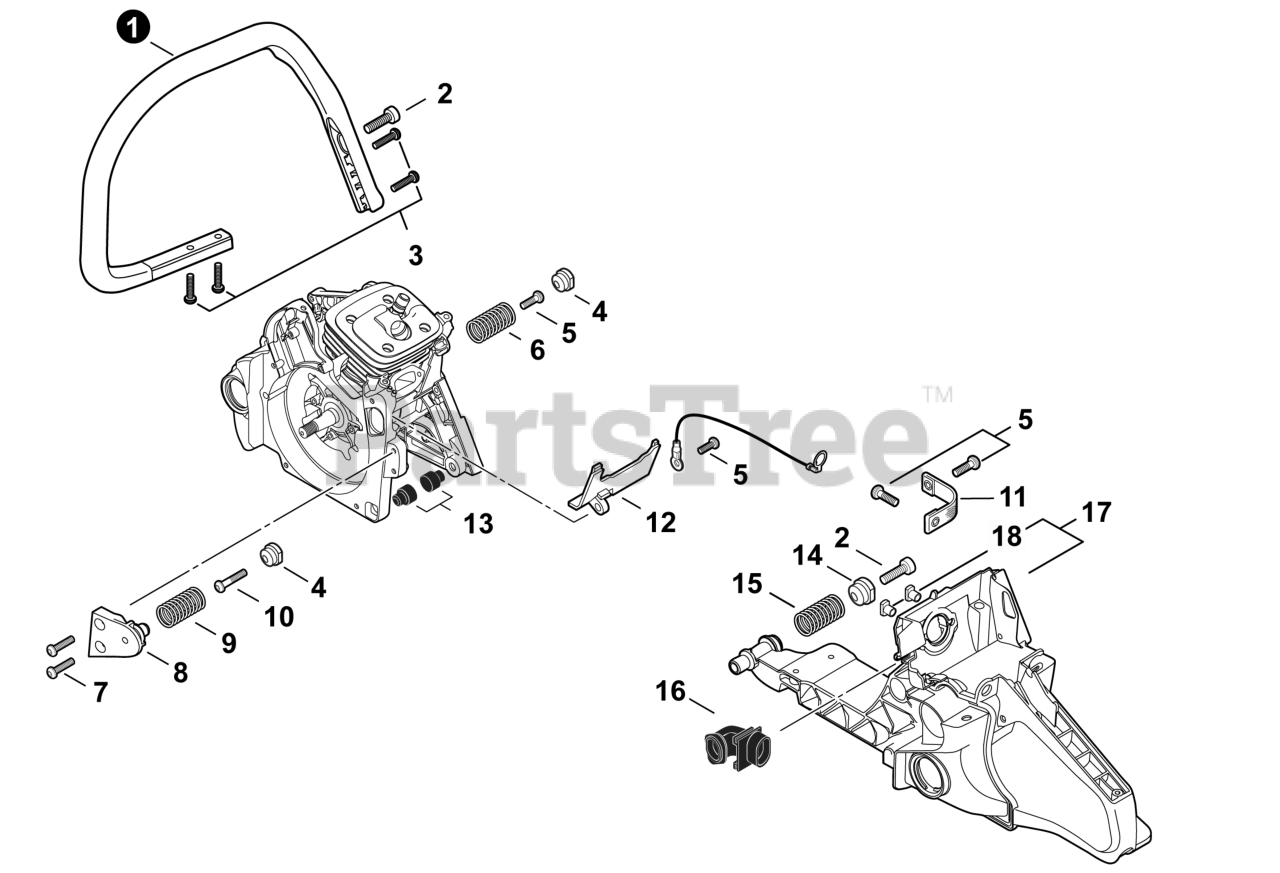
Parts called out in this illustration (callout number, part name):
1	HANDLE, FRONT
2	BOLT, TORX 6x20
3	BOLT, TORX 5x20
4	HOLDER, SPRING 14.4
5	BOLT, TORX 5x16
6	SPRING, COMPRESSION 17x38.4x2.6
7	BOLT, TORX 5x20
8	HOLDER, SPRING
9	SPRING, COMPRESSION 17x36.7x2.6
10	BOLT, TORX 5x25
11	STRAP, SAFETY
12	GUIDE, AIR
13	CUSHION
14	HOLDER, SPRING 17
15	SPRING, COMPRESSION 20x40x3.3
16	PIPE, AIR INTAKE
17	HANDLE, REAR
